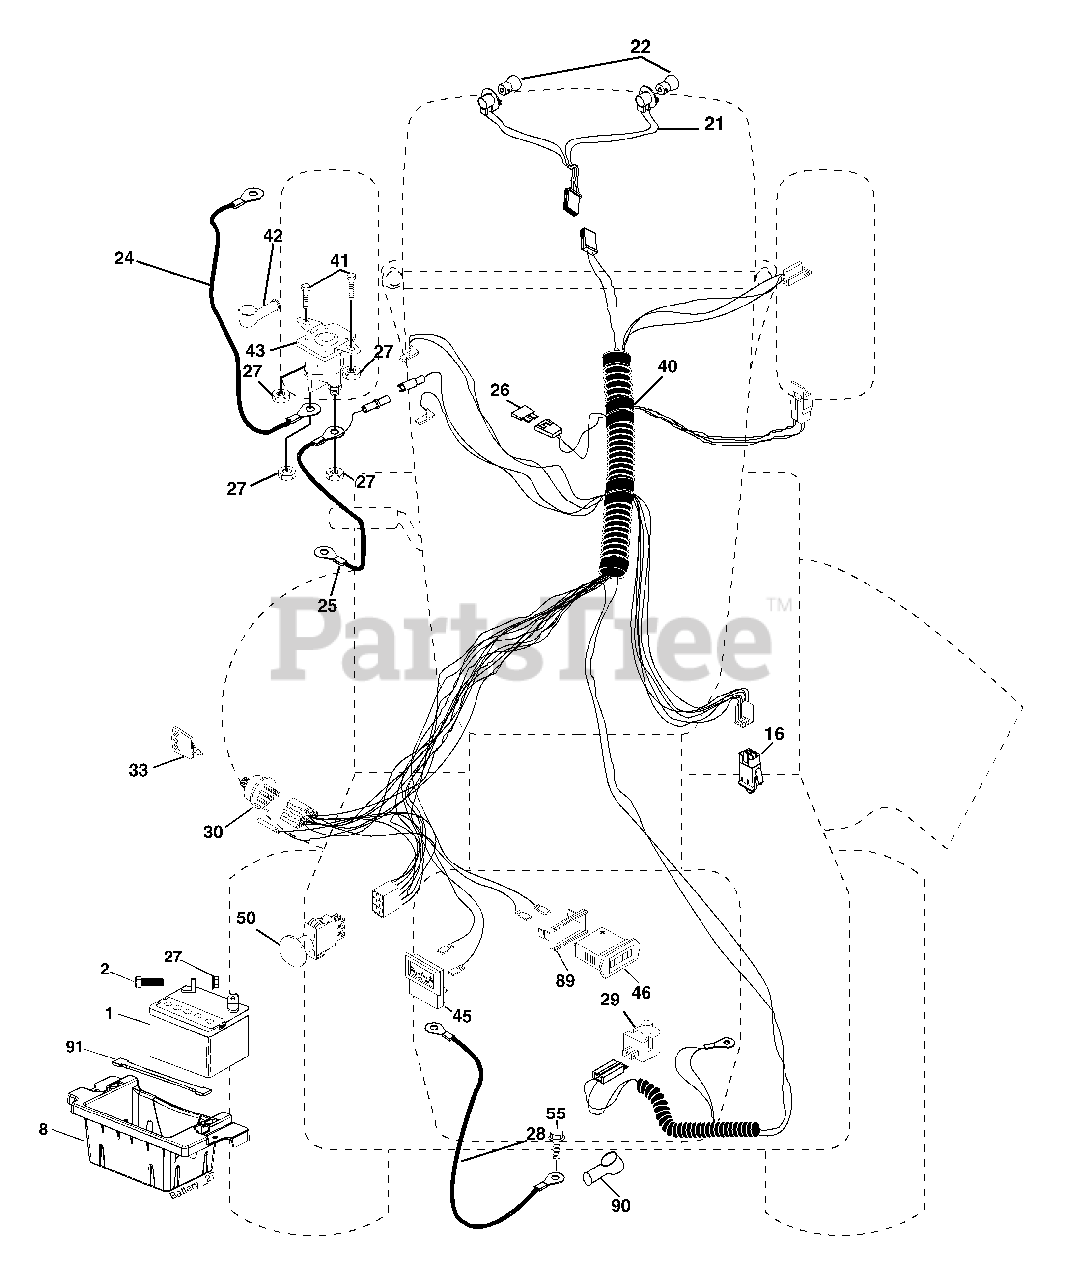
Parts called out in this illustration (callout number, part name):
1	Battery
2	Bolt Hex Hd 1/4-20 unc x 3/4
8	Battery Tray
10	Bolt 1/4-20 x 7.5
11	Holddown Battery Front Mount
12	Nut Push Nylon 1/4"
16	Switch Interlock Push-In
21	Harness Asm Light W/4152j
22	Bulb Light #1156
24	Cable Battery 6 Ga. 11" red
25	Cable Battery 6 Ga. 22" red w/16 wire
26	Fuse 20 AMP
27	Nut Keps Hex 1/4-20 unc
28	Cable Ground black
29	Switch Plunger Nc Gray
30	Switch Ign
33	Key Ign Molded Generic
40	Harness Ign.
41	Bolt Blk Fin Hex 1/4 - 20 x 1/2
42	Cover Terminal Red
43	Solenoid
46	Hourmeter Snap-In
50	Switch PTO
55	Screw 5/16-18 x 1/2
89	Bracket Snap-In Hourmeter
90	Cover Terminal
91	Strap Battery Mount Front
